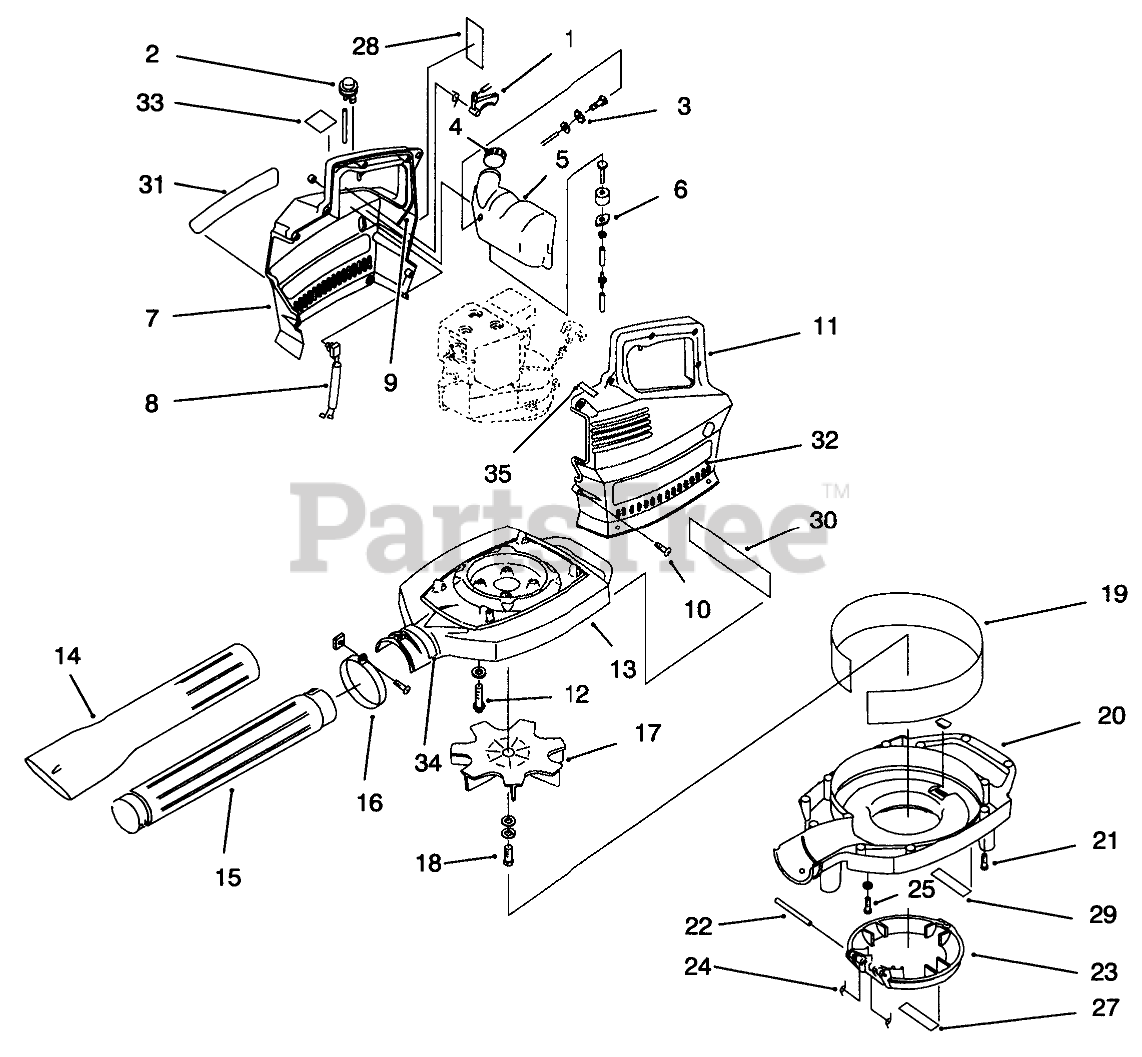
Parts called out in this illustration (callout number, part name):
1	Trigger Asm.
2	ASM-PRIMER BULB & HOSE
3	ASSEMBLY - RETURN LINE
4	FUEL TANK CAP
5	Complete Fuel Tank Asm. (Incl. Ref. #3, 4 and 6)
6	Fuel Line Asm.
7	COVER - RH ENGINE
8	ASM - SWITCH & LEAD
9	ASM-THROTTLE WIRE & HSG
10	SCREW - MOUNTING
11	COVER - LH ENGINE
12	ASSEMBLY - MOUNTING SCREW
13	HOUSING - UPPER BLOWER
14	TUBE - BLOWER W/NOZZLE
15	TUBE - BLOWER
16	ASSEMBLY - CLAMP
17	IMPELLER
18	ASSEMBLY - MOUNTING BOLT
19	SHIELD - IMPACT
20	HOUSING - LOWER BLOWER
21	SCREW - MOUNTING
22	SHAFT - HINGE
23	COVER - INTAKE
24	SPRING SET
25	ASSEMBLY - MOUNTING SCREW
27	DECAL - WARNING
28	Spacer
29	DECAL - PUSH TAB
30	Decal-Fuel & Oil Mix
31	DECAL - RH TORO
32	Decal-Toro L.H.
33	DECAL - PRIME
34	Decal-Safety Symbol
35	Decal-Warning
